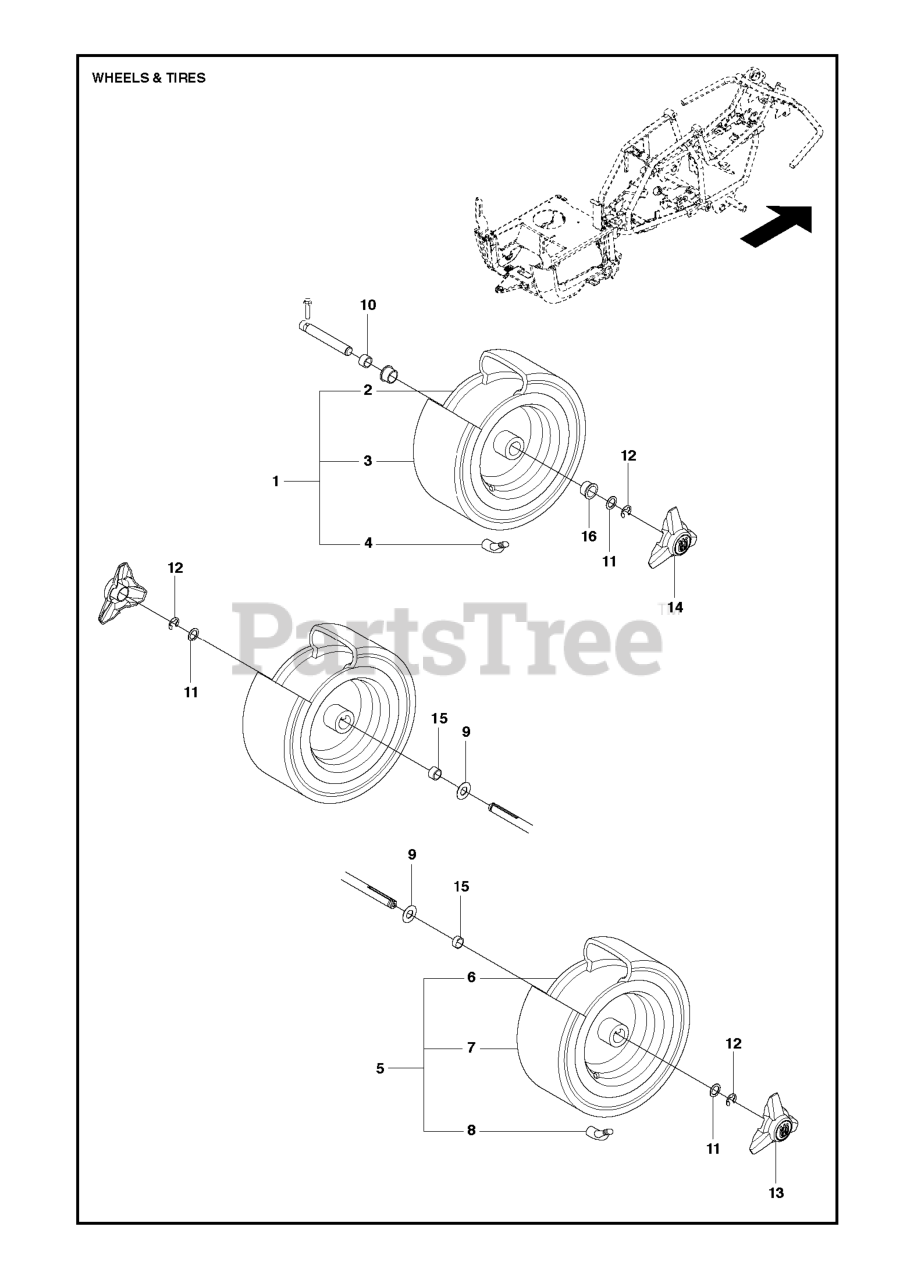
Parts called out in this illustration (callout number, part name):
4	VALVE
8	VALVE
10	SPACING SLEEVE
12	RETAINING RING
